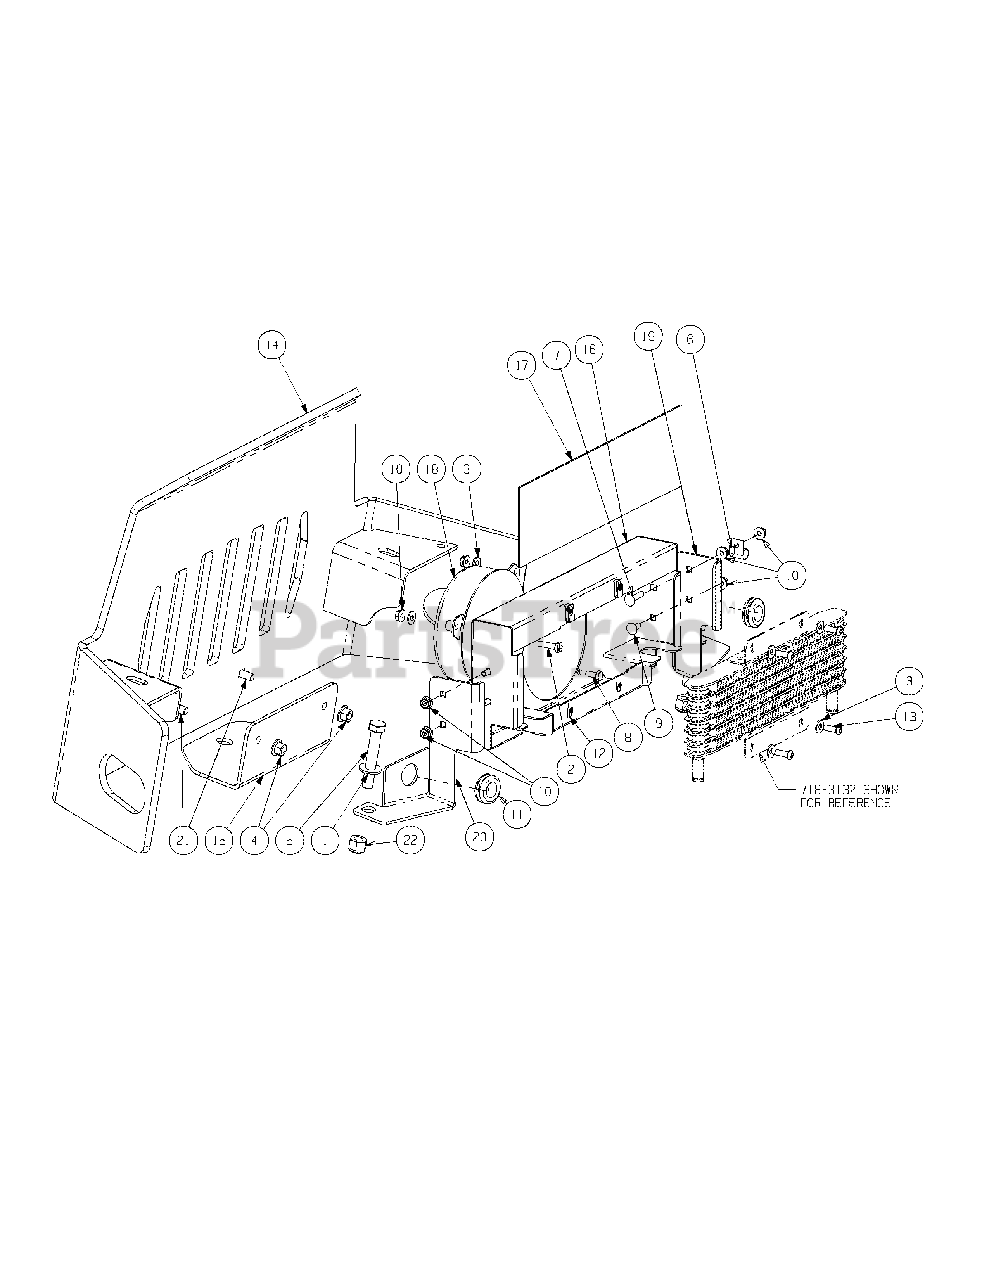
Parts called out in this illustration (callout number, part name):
1	Washer, 1/2
2	Capscrew, 1/4-20 x 1.00
3	Washer, 1/4
4	Nut, Hex 3/8-16 Flange Lock
5	HHCS, 1/2-13, 3.00
6	Clamp, 1/2
7	Carriage Bolt, 1/4-20 x 1.00
8	HHCS, 1/4-20 x .620
9	Carriage Screw, 1/4-20 x .62
10	Nut, 1/4-20, Hex Flange Lock
11	Grommet, .75 ID
12	U-Nut, 1/4-20
13	Capscrew, 1/4-20 x .750
14	Bumper Assembly
15	Hitch Bracket
16	Heat Exchanger Assembly
17	Heat Exchanger Screen
19	Cooler Mounting Bracket, LH
20	Cooler Mounting Bracket, RH
21	Carriage Bolt, 3/8-16 x 1.00
22	Hex Nut, 1/2-13, Insert Lock
